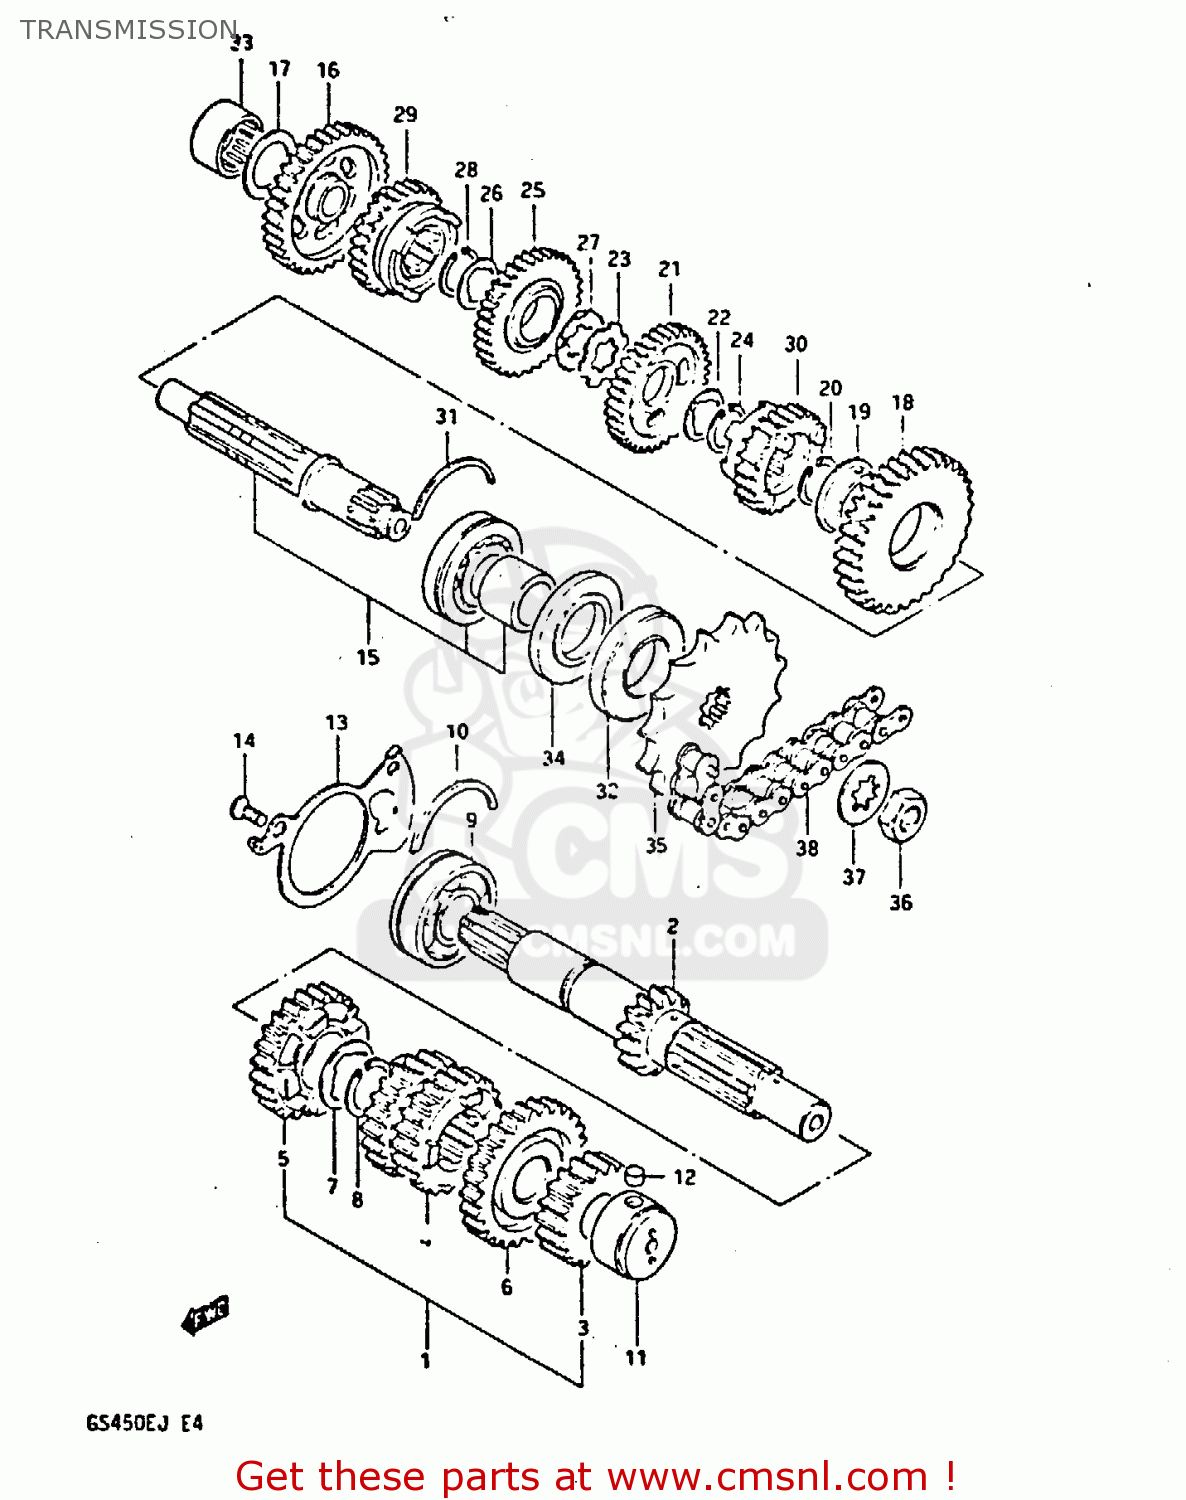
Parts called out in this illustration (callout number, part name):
1	SHAFT,COUNTER
2	SHAFT,COUNTER
3	GEAR,2ND DRIVE(NT:18)
4	GEAR,THIRD DRIVE
5	GEAR,FIFTH DRIVE
6	GEAR,SIXTH DRIVE
7	WASHER
8	CIRCLIP
9	BEARING(25X62X17)
10	C-RING
11	ROLLER BEARING (20X34X2
12	PIN
13	PLATE,COUNTERSHAFT BEARING
14	SCREW
15	SHAFT,DRIVE
16	GEAR,FIRST DRIVEN
17	WASHER
18	GEAR,SECOND DRIVEN
19	BUSHING
20	CIRCLIP
21	GEAR,THIRD DRIVEN
22	WASHER,LOCK
23	WASHER,LOCK
24	CIRCLIP
25	GEAR,FOURTH DRIVEN
26	WASHER,LOCK
27	WASHER
28	CIRCLIP
29	GEAR,5TH DRIVEN(NT:25)
30	GEAR,SIXTH DRIVEN
31	C-RING
32	SEAL,OIL(32X62X7)
33	ROLLER BEARING (20X34X1
34	SEAL,OIL(32X62X5.5)
35	SPROCKET,ENGINE(NT:16)
36	NUT
37	WASHER
38	CHAIN ASSEMBLY,DRIVE
